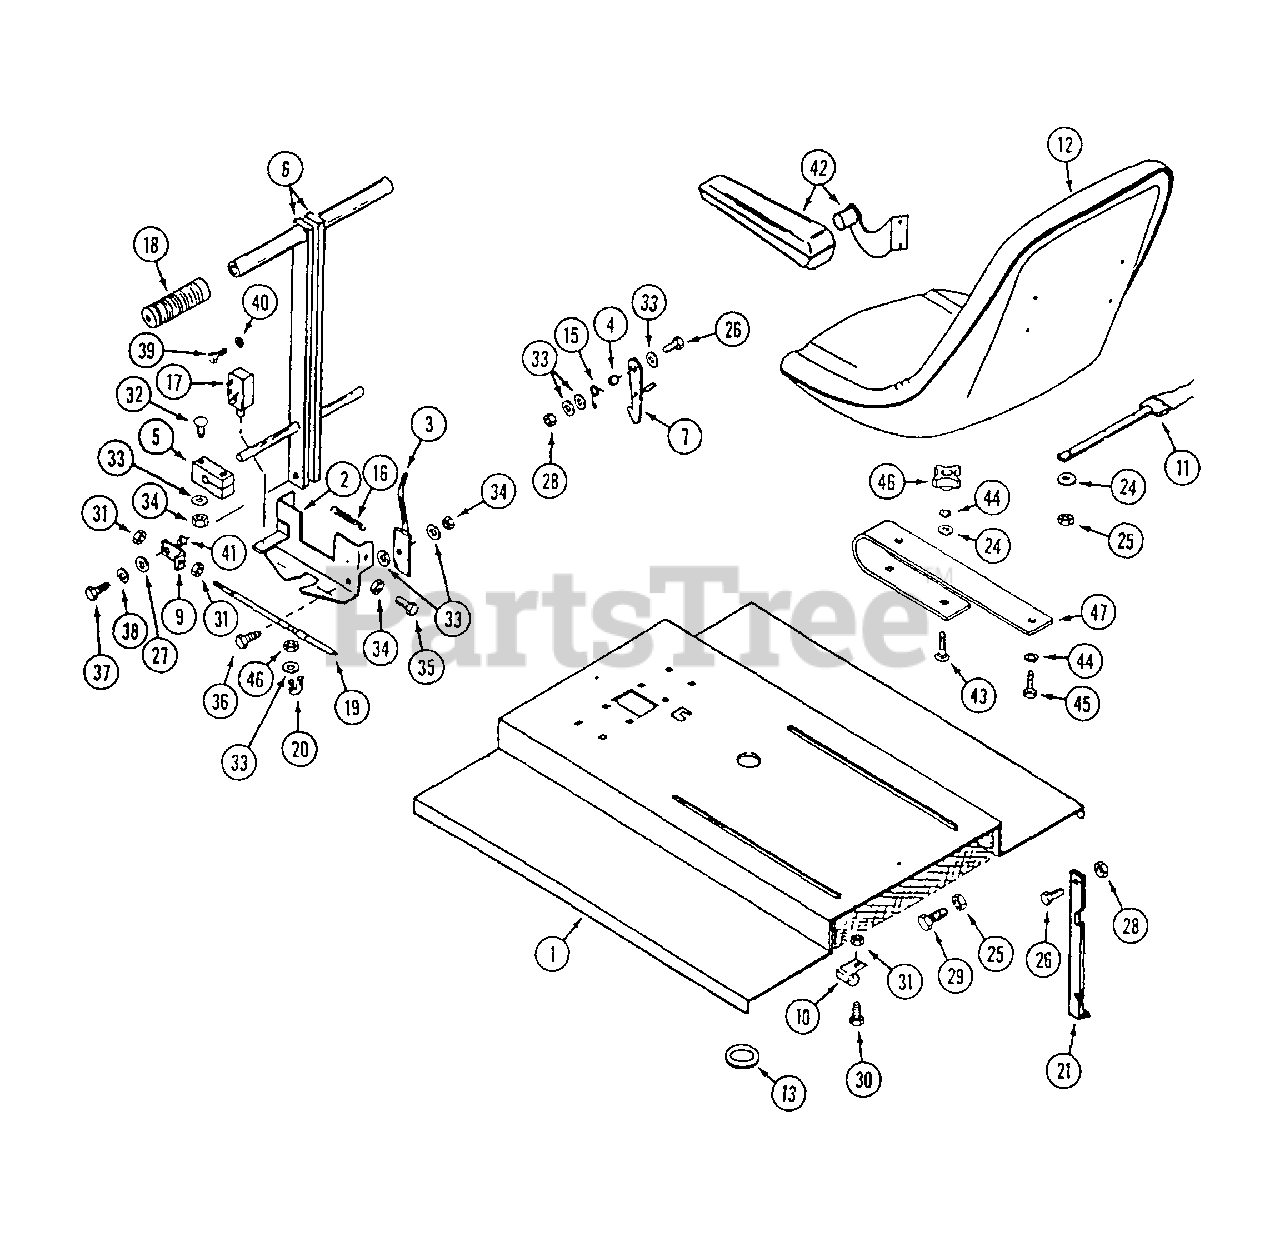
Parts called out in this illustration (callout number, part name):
2	BRACKET - lever lock
3	LATCH - lever lock
4	BUSHING
5	BEARING - block
6	LEVER - steering
7	LATCH - seat lid
9	BRACKET - steering cable end
10	RETAINER - harness, seat lid
11	SWITCH - seat
13	GROMMET - 1" x 1-3/4"
15	SPRING - latch, seat lid
16	SPRING - bracket, lever lock
17	SWITCH - safety
18	GRIP - handle
19	CABLE - steering
20	CLAMP - steering cable
21	PROP - seat lid
24	WASHER - 5/16"
25	NUT - 5/16"
26	BOLT - 1/4" - 20 x 1"
27	WASHER - 1/4"
28	NUT - 1/4" - 20 lock
29	BOLT - 5/16" - 18 x 1"
30	SCREW - #10 - 32 x 1/2"
31	NUT - #10 - 32
32	BOLT - 1/4" - 20 x 1-1/2" carriage
33	WASHER - 1/4"
34	NUT - 1/4" - 20 lock
35	BOLT - 1/4" - 20 x 3/4"
36	BOLT 1/4" - 20 x 2"
37	BOLT - 1/4" - 20 x 3/4"
38	LOCKWASHER - 1/4"
39	SCREW - #10 - 32 x 3/8"
40	LOCKWASHER - 3/16"
41	BUSHING - steering cable
42	KIT - arm rest
43	BOLT - 5/16" - 18 x 1-1/4" carriage
44	LOCKWASHER - 5/16"
45	BOLT - 5/16" - 18 x 1"
47	SPRING - seat
